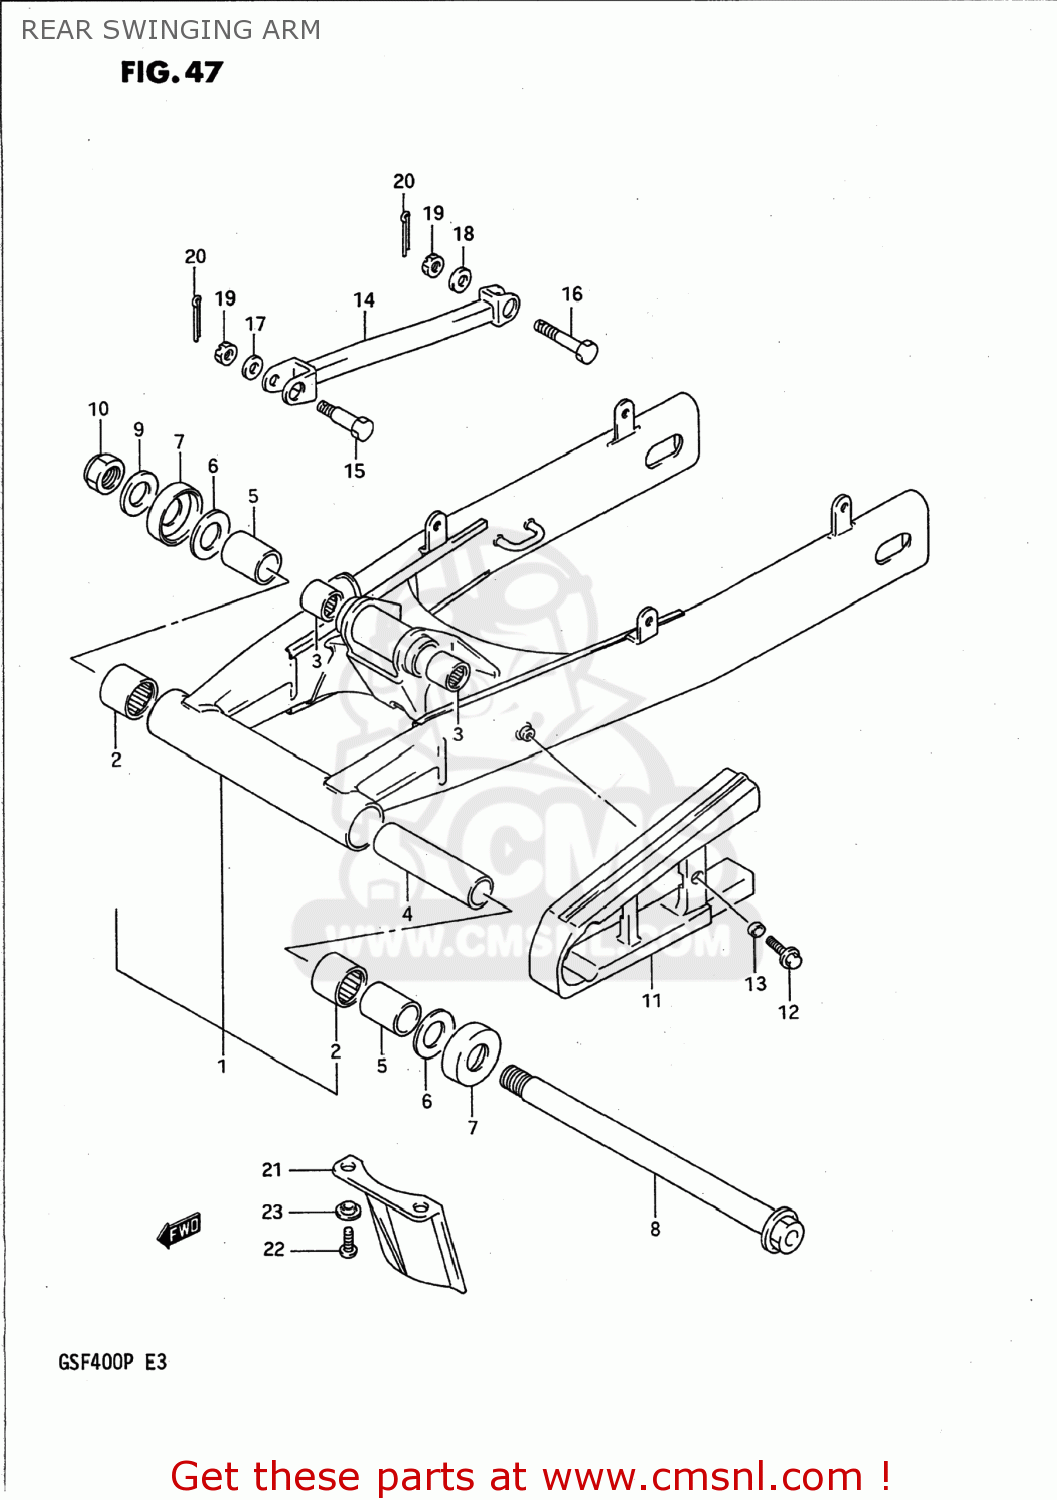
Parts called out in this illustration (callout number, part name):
1	SWING ARM ASSEMBLY,REAR
2	BEARING(25X33X30)
3	BEARING(17X24X25)
4	SPACER(20.8X27.2X146)
5	SPACER,RR SWGARM PIVOT BERRING
6	WASHER
7	COVER,RR SWGARM PIVOT SEAL
8	SHAFT,RR SWINGINGARM PIVOT
9	WASHER
10	NUT
11	BUFFER,CHAIN TOUCH DEFENCE
12	BOLT 6X20,WITH PLAIN WASHER
13	SPACER
14	TORQUE LINK,REAR
15	BOLT
16	BOLT(10X35)
17	WASHER
18	WASHER (10X18X3.2)
19	NUT
20	PIN 20X20
21	GUARD,RR UNIT MUD
22	SCREW
23	WASHER,LOCK
